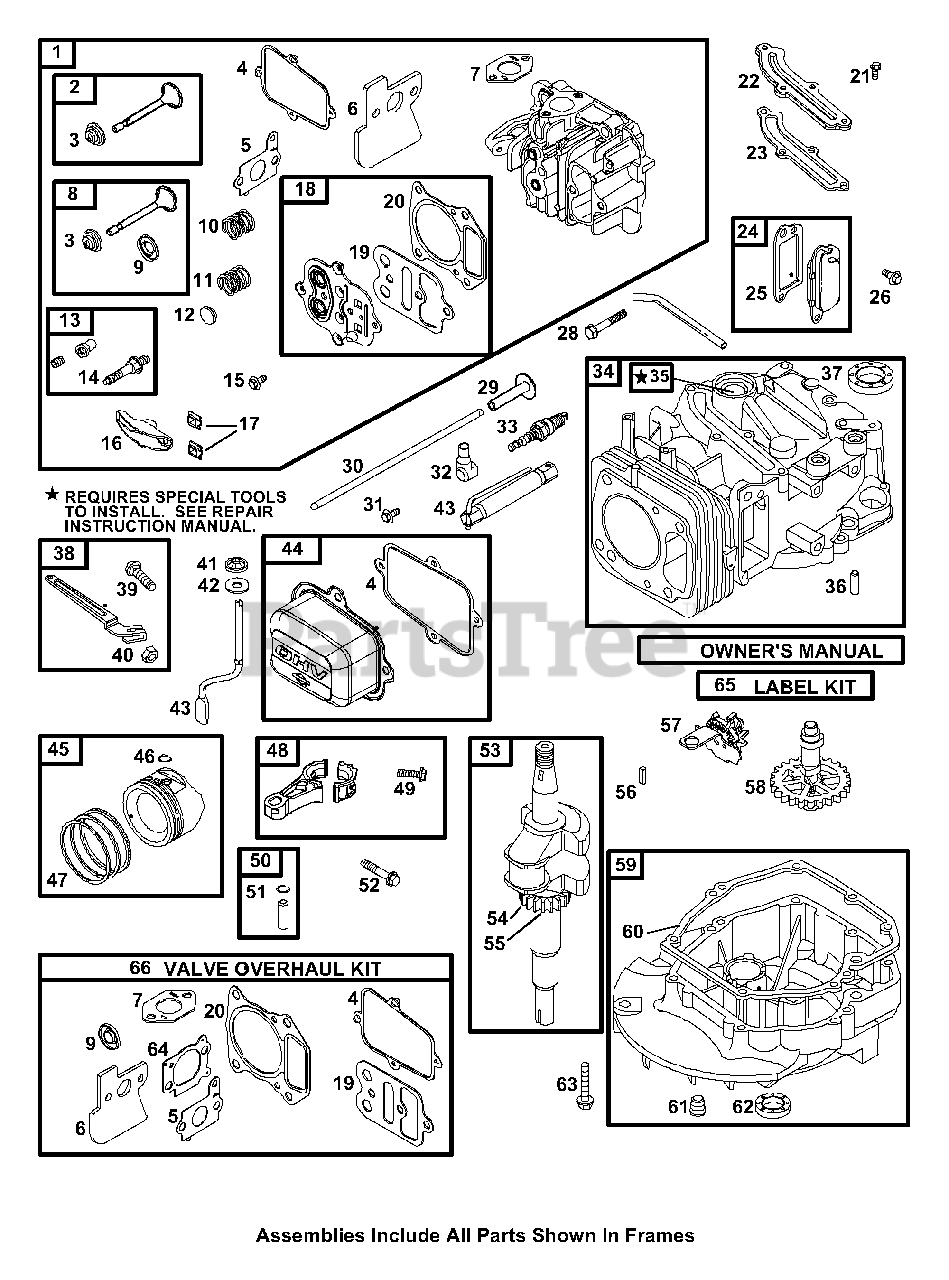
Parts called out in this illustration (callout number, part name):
1	Head-Cylinder
2	Valve-Exhaust
3	Retainer-Valve
4	Gasket-Rocker Cover
5	Gasket-Intake
6	Spacer-Carburetor
7	Gasket-Exhaust
8	Valve-Intake
9	Seal-Valve
10	Spring-Valve (Exhaust)
11	Spring-Valve (Intake)
13	Adjuster-Rocker Arm
14	Stud (Rocker Arm)
15	Screw (Cylinder Head Plate)
16	Arm-Rocker
17	Guide-Push Rod
18	Gasket Kit-Cylinder Head/Plate
19	Cylinder Head Plate Gasket
20	Gasket-Cylinder Head
21	Screw (Breather Passage Cover)
22	Cover-Breather Passage
23	Gasket-Breather Passage
24	Breather Assembly
25	Gasket-Breather
26	Screw (Breather Assembly)
28	Screw (Cylinder Head)
29	Tappet-Valve
30	Rod-Push
31	Screw (Rocker Cover)
32	Boot-Sparkplug
33	Sparkplug
34	Cylinder Assembly
35	Kit-Bushing/Seal (Magneto Side)
36	Pin-Locating
37	Seal-Oil (Magneto Side)
38	Lever-Governor Control
39	Bolt (Governor Control Lever)
40	Nut (Governor Control Lever)
41	Retainer-Governor Shaft
42	Crank-Governor
43	Crank-Governor
44	Cover-Rocker
45	Piston Assembly
46	Lock-Piston Pin
48	Rod-Connecting
49	Screw (Connecting Rod)
50	Pin-Piston
51	Lock-Piston Pin
52	Screw (Connecting Rod)
53	Crankshaft
54	Gear-Timing
55	Key-Timing
56	Key-Flywheel
57	Slinger-Governor/Oil
59	Sump-Engine
60	Gasket-Crankcase
61	Plug-Oil Drain
62	Seal-Oil (PTO Side)
63	Screw (Engine Sump)
64	Gasket-Air Cleaner
66	Kit-Valve Overhaul
